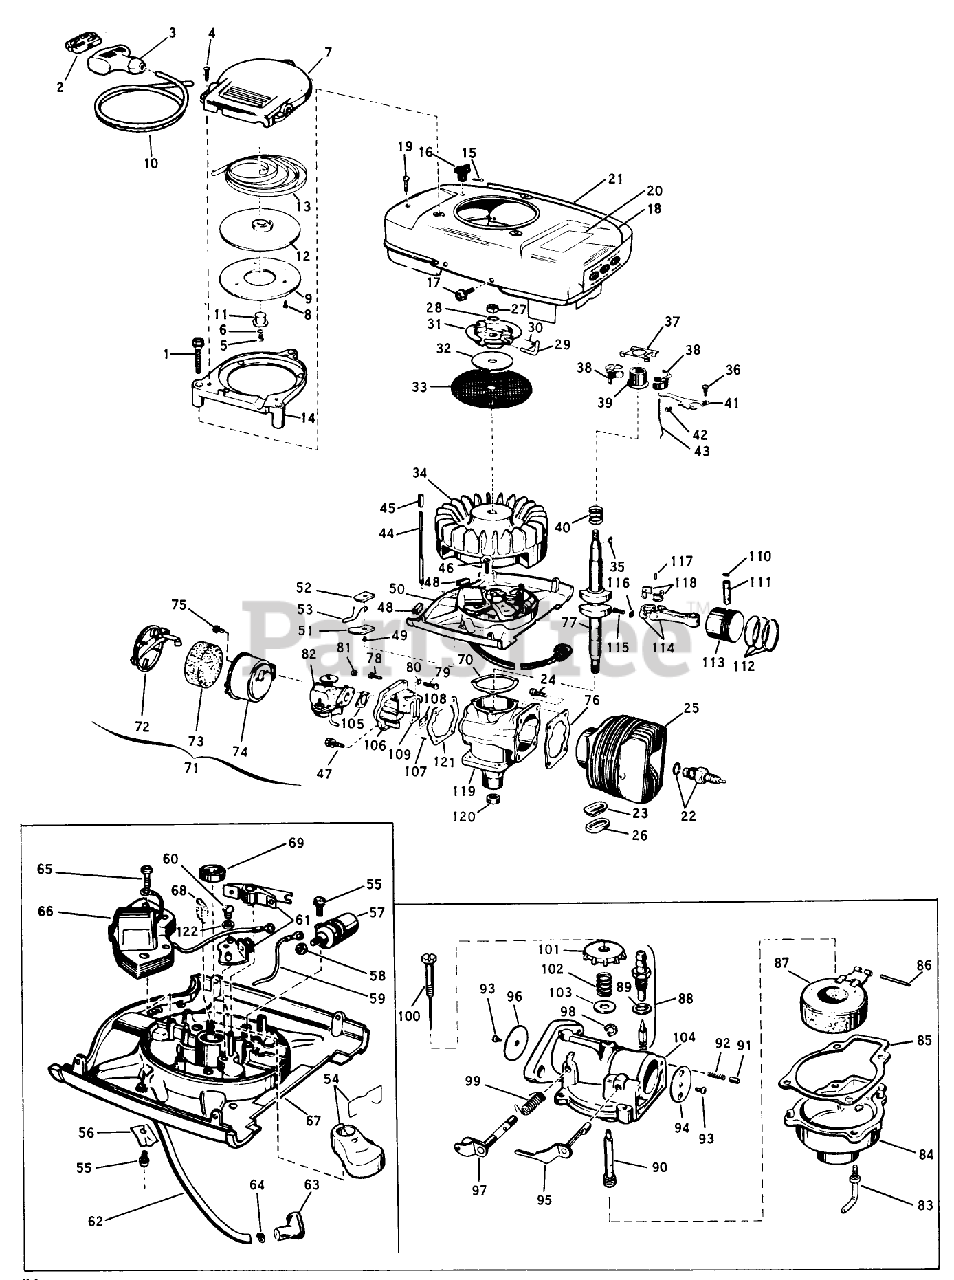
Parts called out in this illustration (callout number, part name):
9	Plate-Pulley
13	RECOIL SPRING
15	Cotter Pin-Choke Knob
16	KNOB, CHOKE BAR
17	SCREW S
22	Spark Plug
26	GASKET S
29	PIN - STARTER
39	COLLAR S
41	GOVERNER LEVER AY
42	WEAR BLOCK S
43	GOVERNOR ROD S
47	SCREW S
49	Screw Shut-off Switch
61	BREAKER AY. S
63	Cover-Rubber
70	GASKET S
73	AIR FIL.ELEM S
75	SCREW S
76	GASKET S
78	SCREW S
81	STOP NUT
93	Screw-Choke Disc
95	CHOKE SHAFT&LVR AY
100	NEEDLE AY. S
102	Spring-Ndl. Adj.
105	GASKET S
108	PLATE-BACKUP, REED
110	RING-RETAINING
118	LINER ASM
